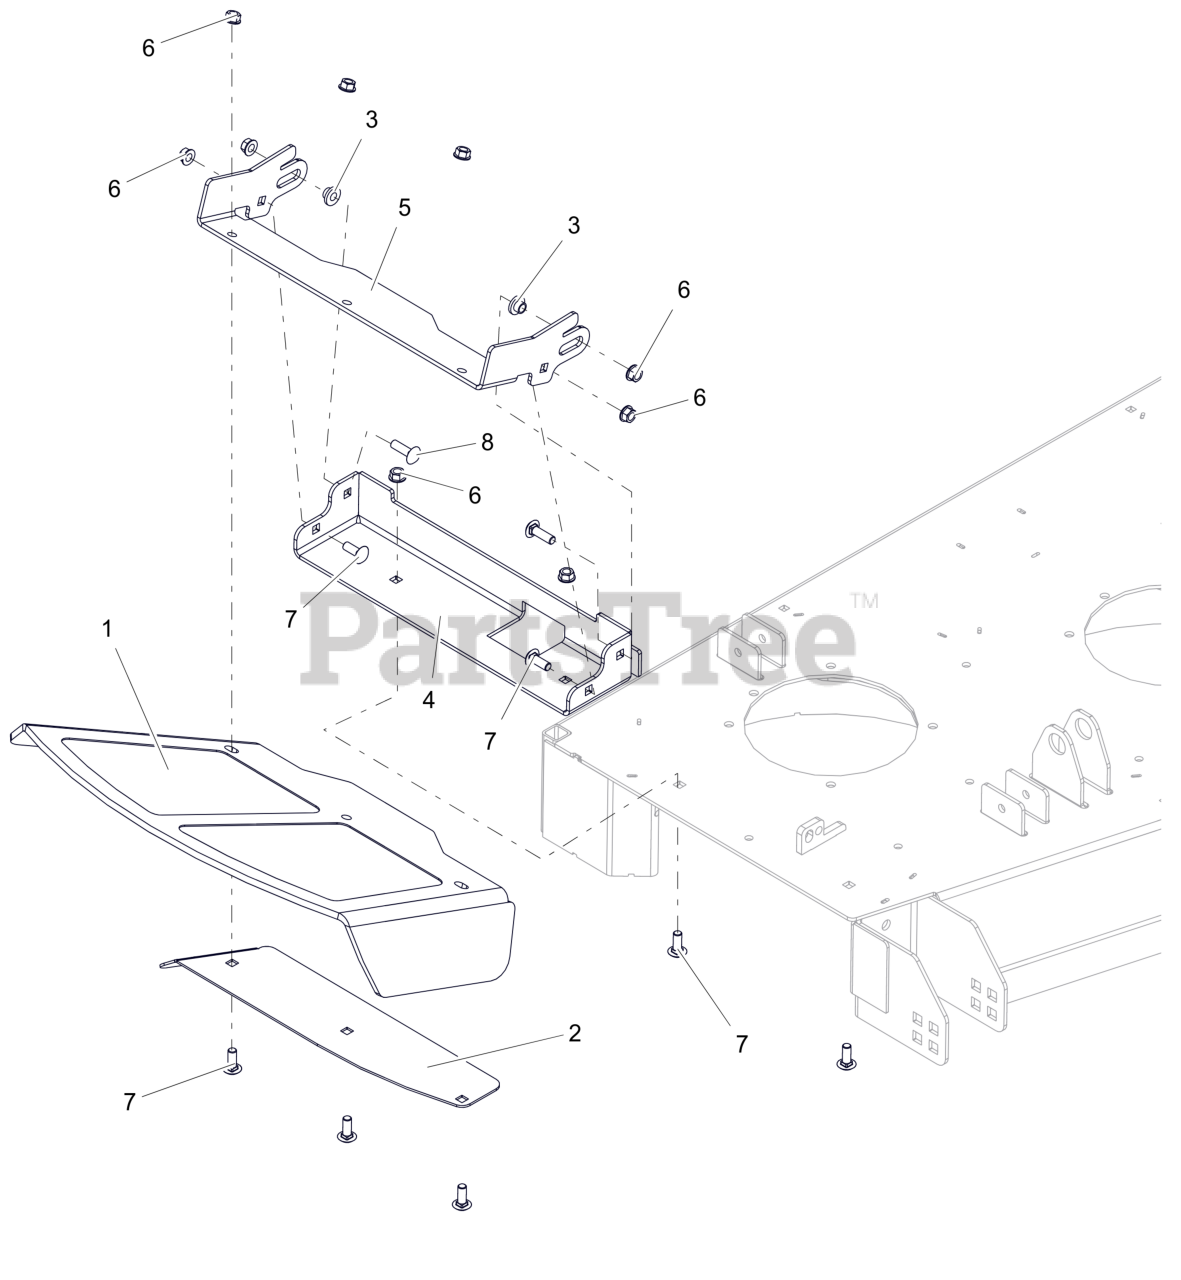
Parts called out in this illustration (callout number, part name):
1	CHUTE, FORMED RUBBER DISCHARGE
2	PLATE, 48-60" DISCH CHUTE CLAMP (BLACK)
3	BSHG-FLG .385X.500X.875X.406
4	BASE- 48" DISCH CHUTE MTG BRKT
5	BRKT- CHUTE MTG
6	NUT-LK-CTR-FLG .375-16 GF ZCC
7	BLT,RHSSN .38-16X1.00 G5 ZCC
8	BLT,RHSSN .38-16X1.25 G5 ZCC
